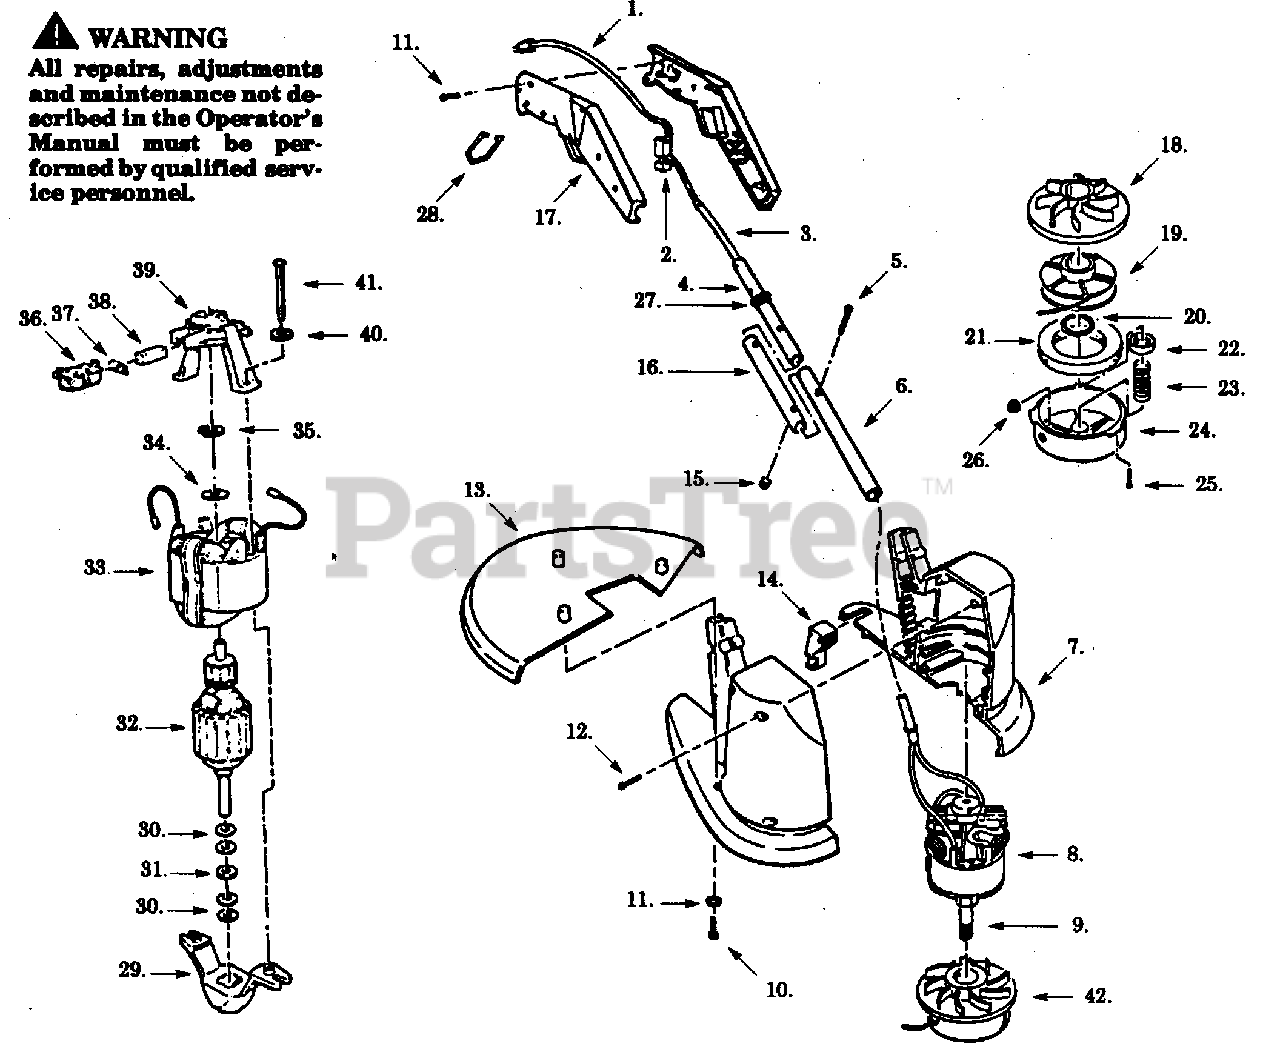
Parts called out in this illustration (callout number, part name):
1	Power Cord
4	Upper Tube
6	Lower Tube
7	R.H./L.H. Housing
9	Drive Adaapter
14	Blade Retainer
16	Outer Tube
17	R.H./L.H. Handle
18	Rear Plate
19	Spool & Line
21	Foam Pad
22	Adapter Nut
24	Hub Ass'y.
25	Cotter Pin
29	Endbell (Drive)
32	Armature Ass'y.
33	Field Ass'y.
36	Brush Holder
37	Brush Spring
39	Endbell (Brush)
40	Lockwasher
42	Cutting Head Ass'y.
